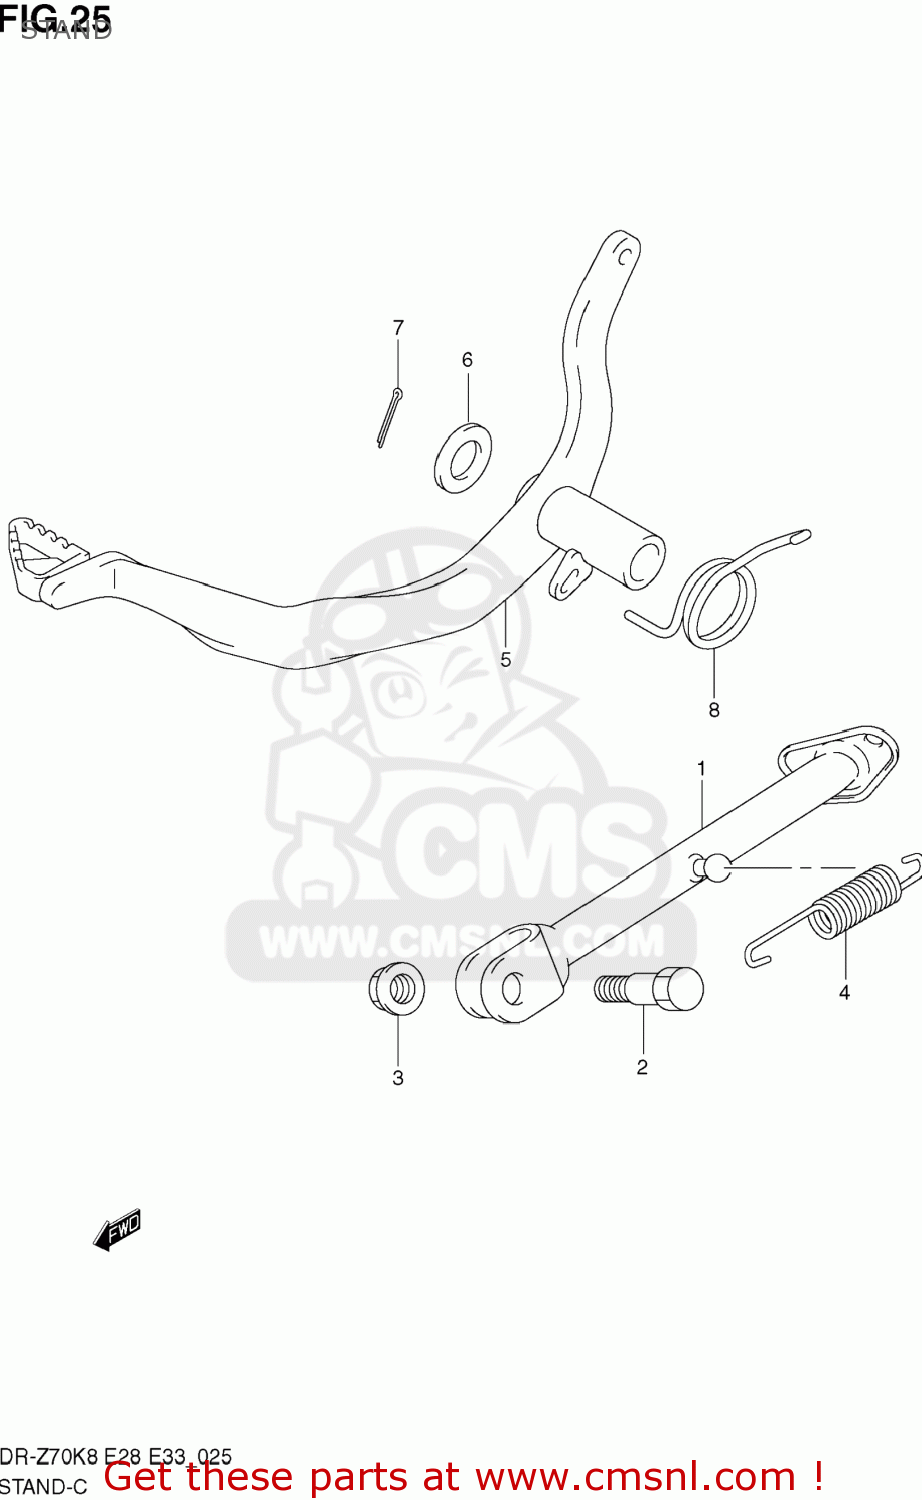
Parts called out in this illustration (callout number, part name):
1	STAND,PROP
2	BOLT(10X33)
3	NUT
4	SPRING
5	PEDAL,BRAKE
6	WASHER(15.5X26X2.3)
7	PIN
8	SPRING
